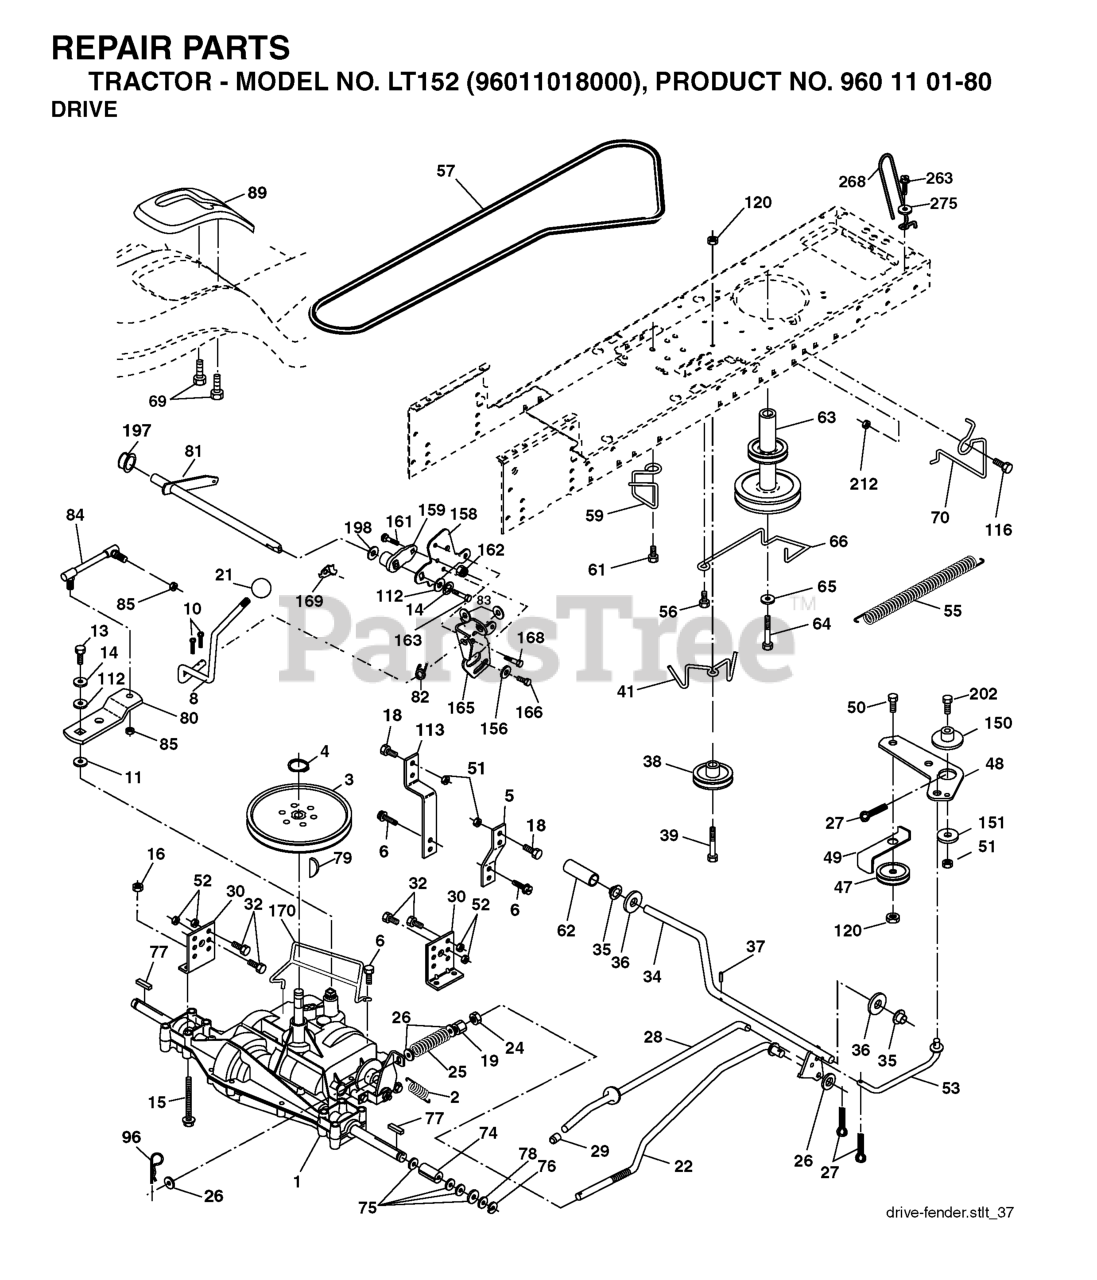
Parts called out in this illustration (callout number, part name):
2	SPRING,BRAKE RETURN
3	PULLEY TRANS
4	RETAINING RING LT
5	STRAP TORQUE
6	SCREW 5/16"
8	ROD.SHIFT.FENDER.ADJ.STLT
10	PIN COTTER
11	WASH-SHFT PLT LT
13	BOLT 1/4-28X3/4
14	LOCKWASHER
15	BOLT HEX 5/16-18 GR 5
16	NUT.71038.31-18.HEX.NYLOCK
18	BOLT
19	NUT
21	KNOB.DUCKHEAD.1/2
24	NUT
25	SPRING ROD LT
26	WASHER
27	COTTER PIN
28	ROD, PARKING BRAKE
29	PLUNGER CAP
30	BRKT, MOUNT TRNSAXLE
32	BOLT
34	SHAFT, FOOT PEDAL
35	BEARING.NYLON
36	WASHER LT
37	DRIVE PIN
38	PULLEY IDLER COMPOSITE
41	KEEPER, BELT IDLER
47	IDLER PULLEY
48	BELLCRANK, CLUTCH
49	RETAIN BELT
50	BOLT.3/8-16X1.50
52	LOCKNUT
53	LINK.CLUTCH.7.66.2005
55	SPRING, RETURN LT
56	SCREW.3/8-16
57	BELT, V GROUND DRIVE 95 25
59	KEEPER, BELT CENTER
61	SCREW 3/8-16X.875
62	PEDAL COVER T
63	ENGINE PULLEY
64	BOLT HEX 7/16-20X4-1/4"
65	LOCKWASHER
66	KEEPER BELT ENGINE
69	SCREW.HI-LO.CONSOLE
70	KEEPER BELT ENG
74	SPACER AXLE
77	SQUARE KEY
79	KEY STD (1373) DANA
81	SHAFT ASM CROSS TAPERED
82	SHIFT SPRING
83	WASHER
84	LINK.TRNSAXLE
85	NUT LOCK CENTER 1/4 -28 FNTHD
89	CONSOLE.SHIFT.STLT.6SP
96	RETAINER M
112	WASHER LT
113	STRAP TORQUE LH LT
116	BOLT D
120	NUT LOCK FLG 3/8-16 UNC
150	SPACER, RETAINER
151	WASHER 12/32X2X10GA
156	WASHER.SRRTD.5/16
158	BRACKET
159	RB HUB.SHIFT
161	BOLT
162	NUT.CROWNLOCK.1/4
163	BOLT
165	RP BRACKET
166	CAPSCREW.HXHD.FLG.5/16-18X.625
168	BOLT.SHOULDER.5/16-18X
169	PLATE.FASTENING.CROSS.SHAFT
170	KEEPER BELT T/A
197	NYLINER SNAP 5/8" ID
198	WASHER.NYL.7/8IDX.105"HYD CR
212	NUT
263	SCREW, 3/8-16X3/4
268	GUARD MUFFLER
275	WASHER
